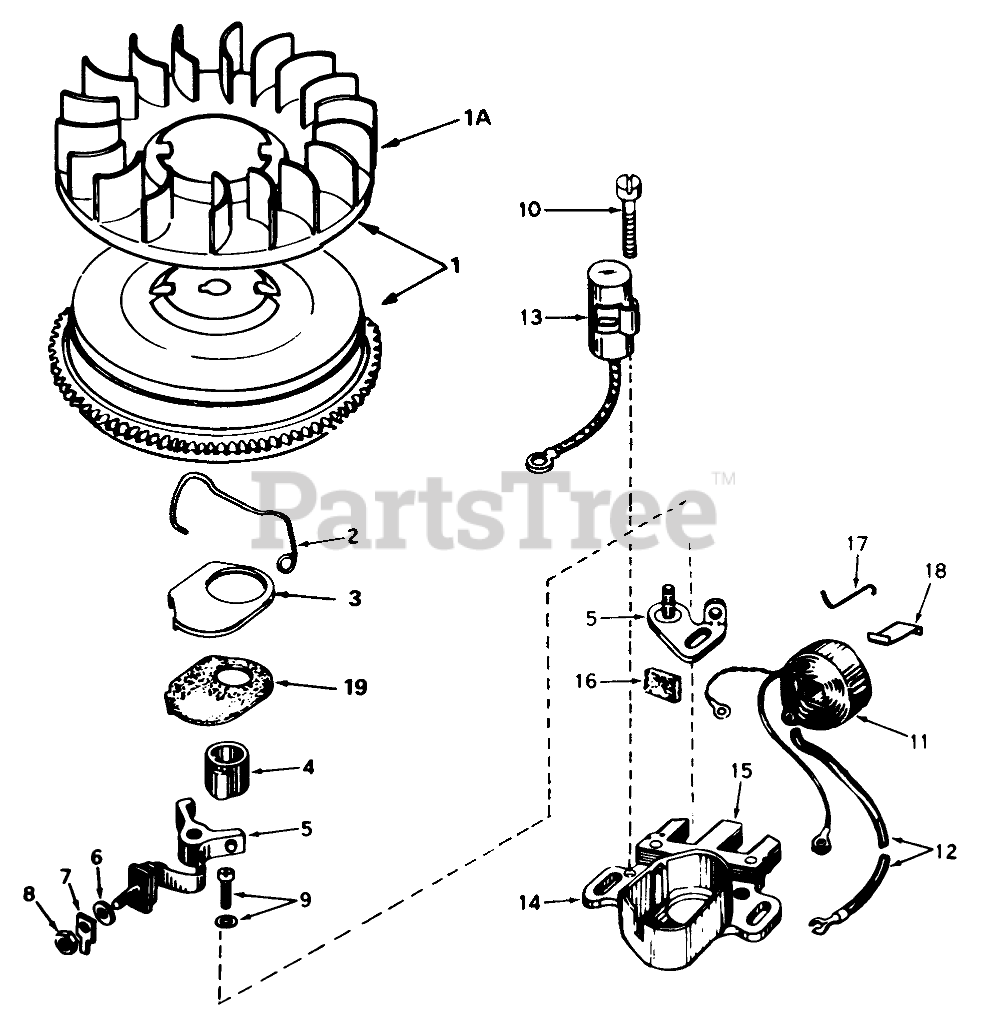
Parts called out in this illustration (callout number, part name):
1	Flywheel (Incl. Ref. #1A)
1A	Fan
2	Spring Breaker Box
3	Cover-Dust
4	Cam-Breaker
5	Breaker Assy.
6	Washer
7	Terminal, Ground
8	DECAL
9	Breaker Screw
10	Condenser Screw
11	Coil Assy. (Incl. Ref. #12)
12	Wire, Lead
13	Condenser
14	Core & Plate
15	Stator Assy. (Incl. Ref. #2, 3, 5 thru 14 & 16 thru 19)
16	Felt,Cam Wiper
17	Clip, Coil
18	Spring Coil Wedge
19	Gasket-Dust Cover
